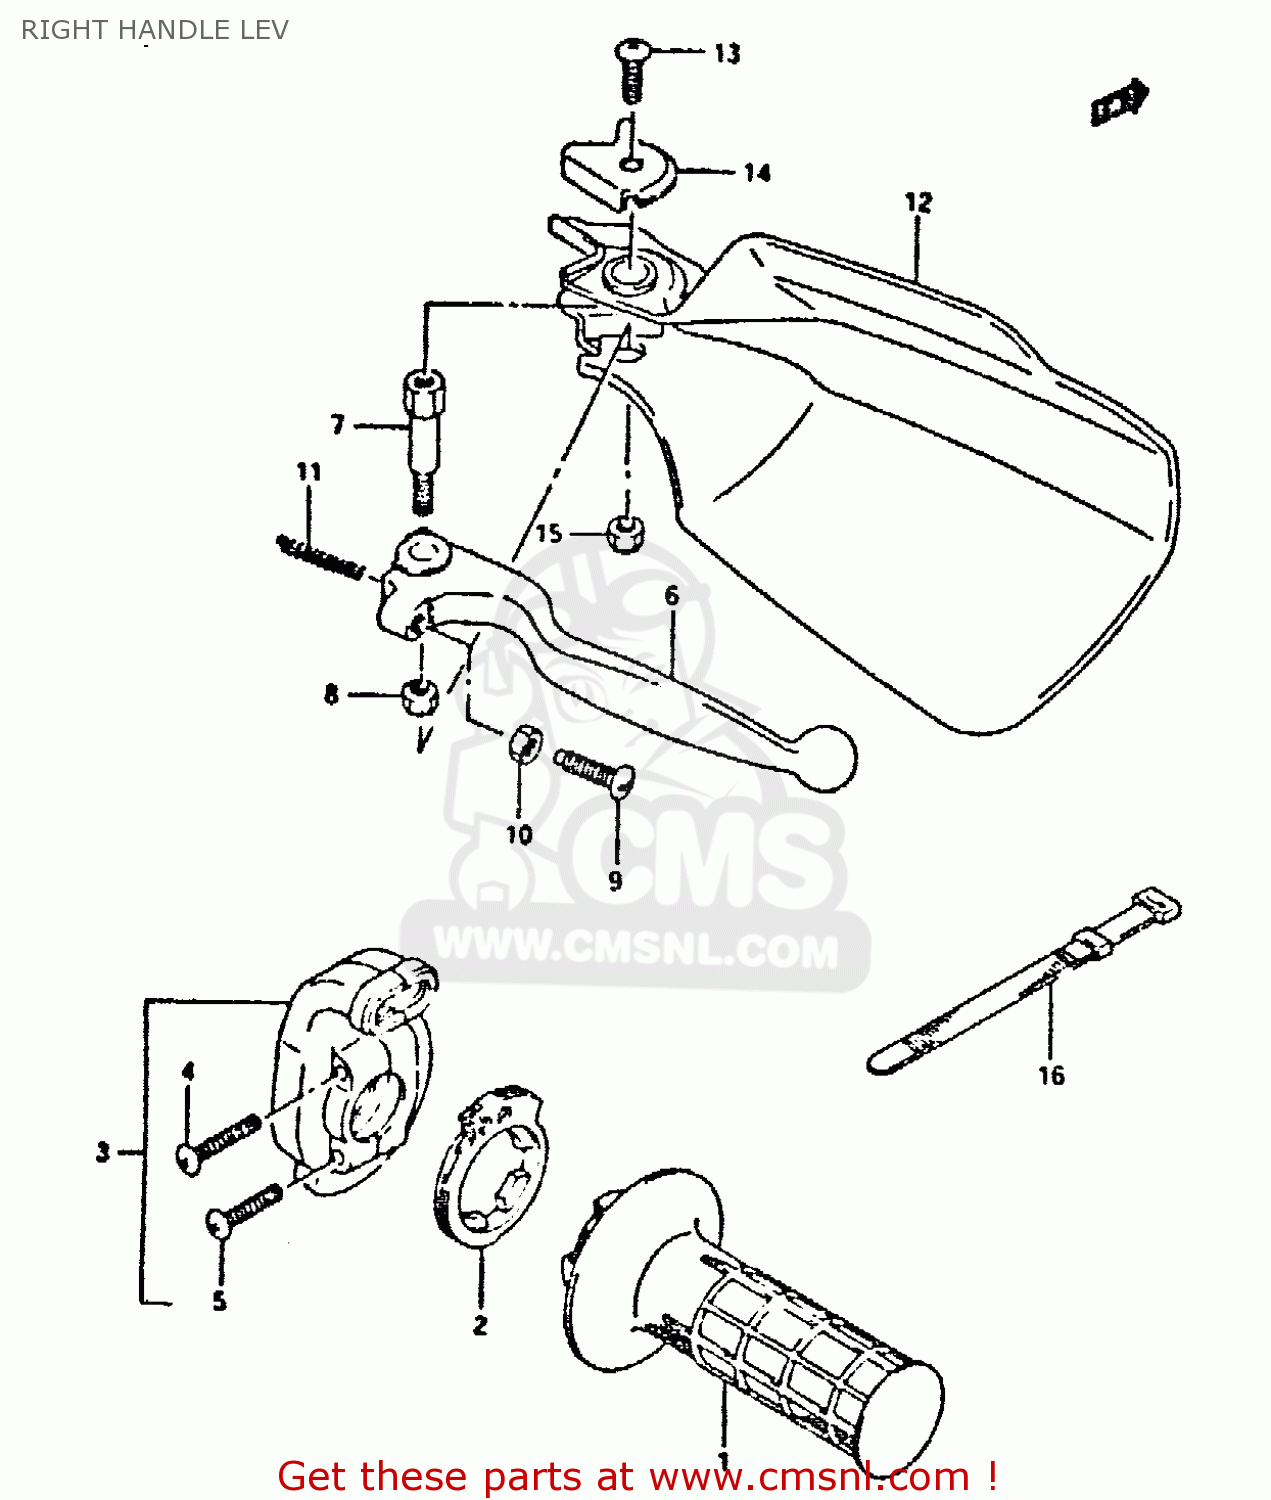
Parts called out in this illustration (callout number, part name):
1	GRIP,THROTTLE
2	ROTOR,THROTTLE GRIP
3	CASE ASSY,THROTTLE
4	SCREW(5X25)
5	SCREW 5X20
6	LEVER,BRAKE
7	BOLT,BRAKE LEVER PIVOT
8	NUT 6MM
9	BOLT,ADJUST
10	NUT ,5MM
11	SPRING,RETURN
12	COVER,KNUCKLE,R
13	SCREW
14	PLATE,KNUCKLE COVER,R UPR
15	NUT 6MM
16	CLAMP(L:120)
